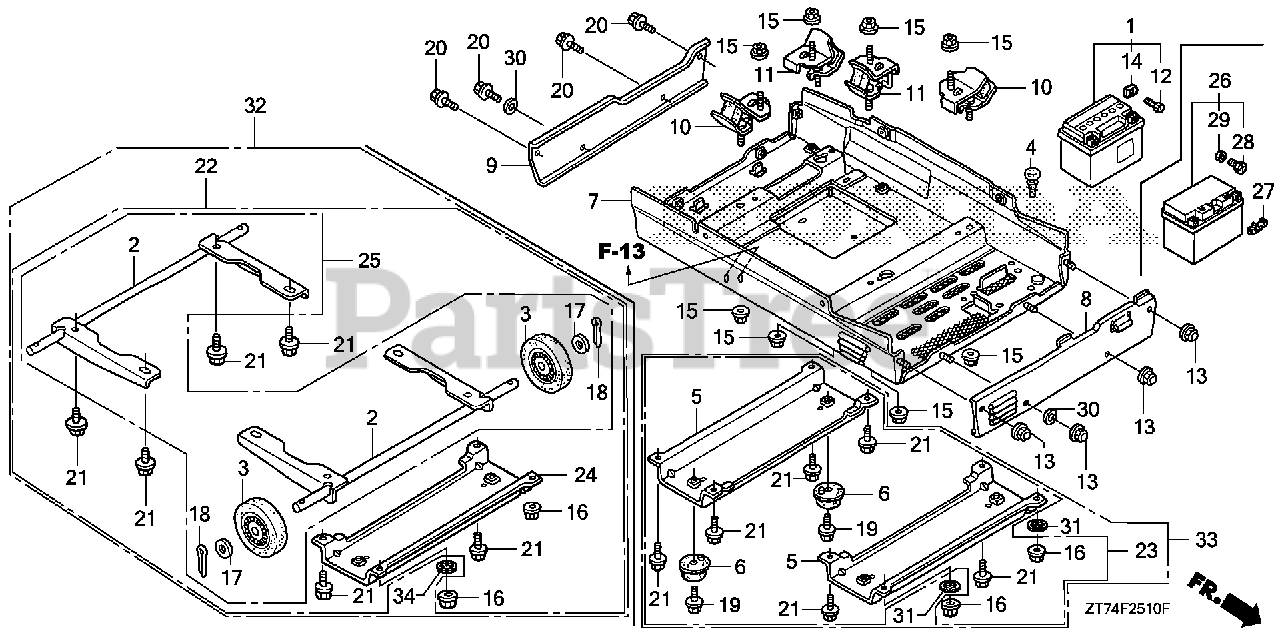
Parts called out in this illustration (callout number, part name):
1	BATTERY (YTX9-BS) (YUASA) (MSDS)
2	SHAFT, WHEEL
3	WHEEL (100X32)
4	RUBBER, STAND STOPPER
5	STAND
6	RUBBER (LOWER)
7	COVER (LOWER)
8	PLATE, FR. (LOWER)
9	PLATE, RR. (LOWER)
10	RUBBER, R. (LOWER)
11	RUBBER, L. (LOWER)
12	BOLT, BATTERY TERMINAL (NOT AVAILABLE)
14	NUT, BATTERY TERMINAL (NOT AVAILABLE)
15	NUT, FLANGE (8MM)
16	NUT, FLANGE (8MM)
17	WASHER, PLAIN (12MM)
18	PIN, SPLIT (4.0X20)
19	BOLT, FLANGE (6X10)
20	BOLT, FLANGE (6X10)
21	BOLT, FLANGE (8X14)
22	WHEEL KIT
23	STAND KIT
24	STAND
25	WHEEL KIT
